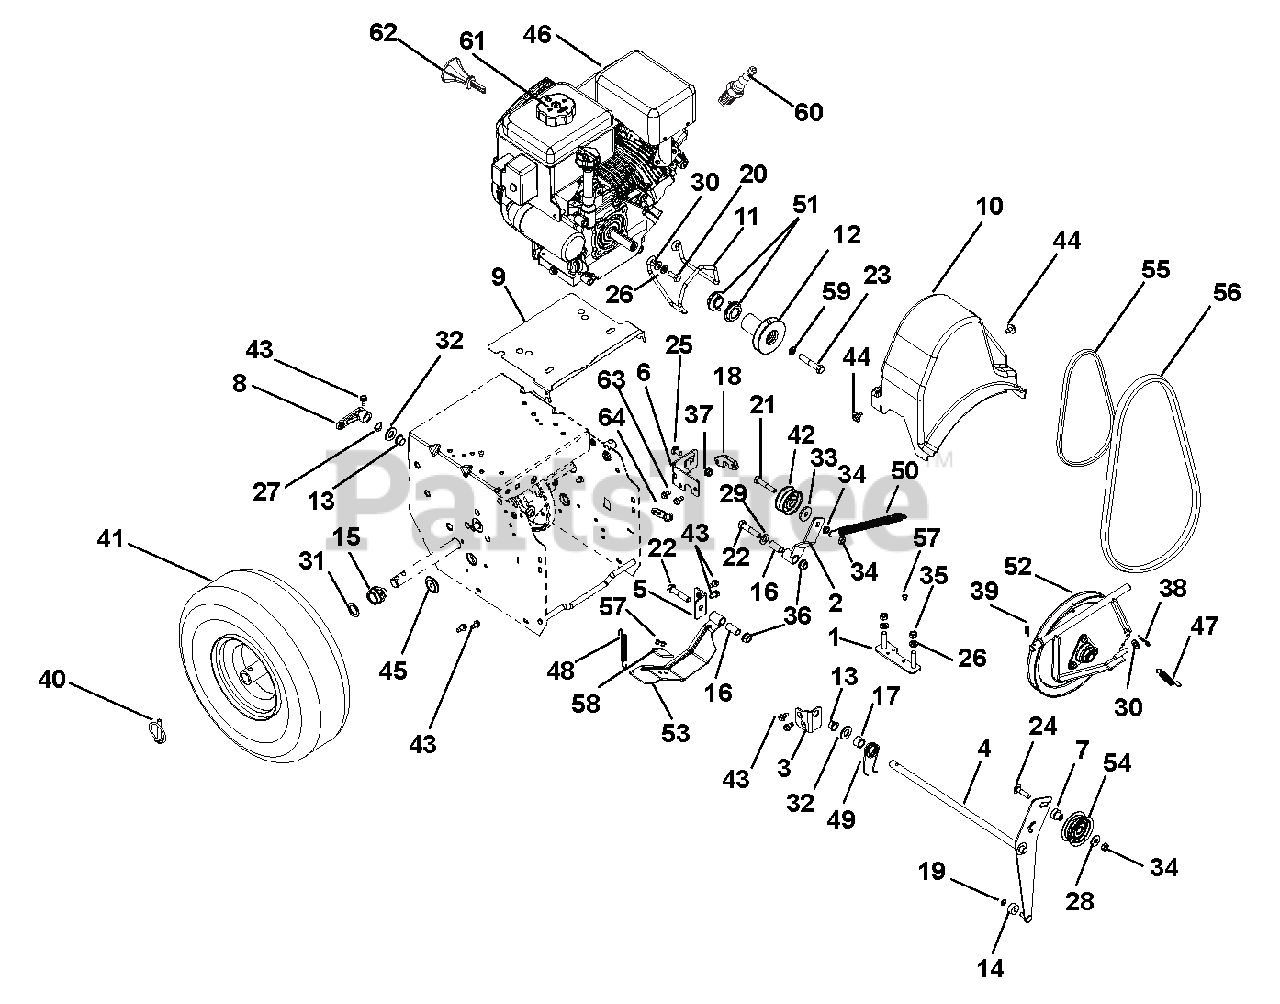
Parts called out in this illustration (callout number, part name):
1	STRAP, ENGINE BOLT-WELDMENT
2	WELDMENT, TRACTION IDLER ARM
3	BRACKET, MOUNT - IDLER ARM
4	WELDMENT, ATTACHMENT IDLER ARM
5	BRACKET, MOUNT - BRAKE
6	WELDMENT, FRAME BRACKET
7	SPCR, BRG .315X.50X.688X.281
8	ARM, CLUTCH - ATTACHMENT
9	BAFFLE,ENGINE,SMALL BLOCK
10	COVER, COMPACT BELT
11	FINGER, BELT
12	SHEAVE, AUGER - COMPACT
13	BUSHING, POLYLINER-.50 SPLIT
14	BSHG,SLV .265 X .625 X .375
15	BSHG .75X1.125X.65
16	BSHG-SLV .385X.500X1.045
17	BSHG-SLV .510X.751X.475
18	SPACER, SWING GATE
19	RG-RTNG-EXT .250X.010
20	BLT-HEX .31-24X.75 YWZC GR5
21	@BLT-HEX .31-18X1.75 GR5 YWZC
22	@BLT-HEX .38-16X1.75 GR5 YWZC
23	BLT-HEX .38-24X2.0 YWZC
24	BLT-RDHDSQSHNK.31-18X1.13 G5YZ
25	@BLT-RHDSSQNK .31-18X.62 G5YZ
26	WSHR-LK .312X.097 HVY YWZC
27	WSHR-WAVE .50X.75X.015 .13FRHT
28	@WSHR-FL-STL.38X.875X.083 YWZC
29	@WSHR-FL-STL.406X.812X.065 YWZ
30	@WSHR-FL-STL.344X.688X.065YWZC
31	WSHR-FL-STL.754X1.125X.062YWZC
32	@WSHR-FL-STL.531X1.06X.095YWZC
33	WSHR-FL-STL .344X1.125X.135
34	@NUT-LK-CTR-JAM .31-18 YWZC
35	@NUT-HEX .31-18 YWZC
36	@NUT-LK-TOP-FLG .38-16 YWZC
37	@NUT-LK-TOP-FLG .31-18 YWZC
38	PIN-HAIR INT .08X.18X1.18 YWZC
39	CLIP, SPRING
40	PIN-LOK .31X1.75
41	TIRE/WHEEL, 13X4.10-6 K398A
42	IDLER,1.875" OD
43	SCR-TAP .25-20X.50 HWH TR YWZ
44	SCR-TAP .25-20X.5 CAPTIVE
45	PLUG, HOLE - 1.00" FLEXTEMP
46	ENGINE,LCT STORMFORCE 208 RECL
47	SPRING, EXT. .043X.438X1.64
48	SPRING-EXT .437 X .438 X 2.64
49	SG-TORS .075 X .955
50	SPRING, EXTENSION
51	TRACTION SHEAVE HALF
52	PLATE, SWING - ASSEMBLY
53	BRAKE ARM W/PAD
54	IDLER
55	V-BELT, 3L-WRAPPED
56	V-BELT, HA-RAW EDGE
57	RVT-POP .187 YZ
58	PAD, BRAKE
59	@WSHR-LK .38X.094 REG YWZC
60	PLUG, SPARK
61	CAP, FUEL TANK BLACK
62	KEY, PUSH/PULL LCT (2/PACKAGE)
63	SCR-TAP .25-20X.75 HWH TR YWZ
64	SUPPORT BUSHING, SWING GATE
